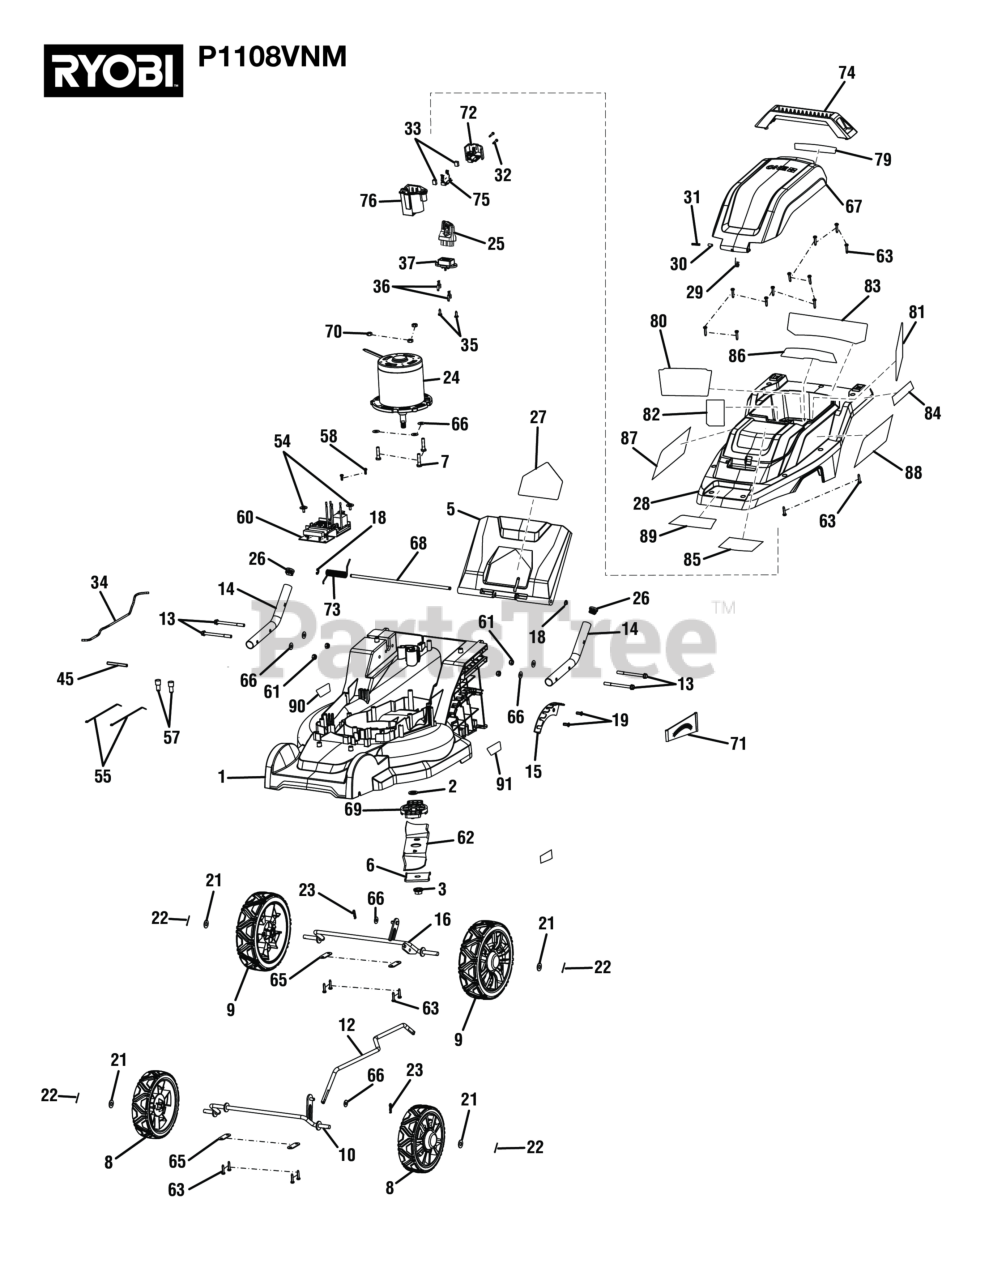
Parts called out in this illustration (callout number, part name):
1	Deck Assembly
2	Flat Washer
3	Blade Nut (M10 x 1.25, Hex Flange Hd.)
5	Rear Door (Inc. Key No. 27)
6	Blade Retainer
7	Bolt (M6 x 26 mm, Hex Hd.)
8	6 in. Wheel Assembly
9	7 in. Wheel Assembly
10	Front Wheel Axle
12	Connector Rod
13	Screw (M6 x 70 mm, Hex Hd.)
14	Tube on Deck
15	Height Adjustment Plate
16	Rear Wheel Axle
18	E-ring (Retaining Ring)
19	Screw (#10-14 x .543 in., T25 Torx Hd.)
21	Washer (ID8.4 x OD18 x 1t)
22	Cotter PinÏ? (2.5)
23	Hitch Pin
25	Start Key
26	Tube Plug
27	Danger Label (No Hands/Feet)
28	Top Cover (Inc. Key Nos. 80-89)
29	Torsion Spring
30	Battery Door Axle
31	Compression Spring
32	Screw (M3 x 16 mm, T10 Torx Hd.)
33	Rubber Cushion
34	Circuit Board to Terminal Wire (Red)
35	Screw (M4.2 x 12 mm, T20 Torx Pan Hd.)
36	Female Terminal
37	Key Holder
45	TUBE, BLK. SHRINKABLE, 5MM
54	Screw w/Washer (M4-18 x 10 mm, T20 Torx Pan Hd.)
55	Cable Tie
57	Wire Connector
58	Screw (M4 x 10 mm, T20 Torx Pan Hd.)
60	Circuit Board
61	Lock Nut (M6 x 6 mm)
62	13 in. Blade
63	Screw (M4 x 18 mm, T20 Torx Pan Hd.)
65	Axle Pressure Plate
66	Washer (ID6.2 x OD15 x 0.08t)
67	Battery Cover (Inc. Key No. 79)
68	Rear Door Shaft
69	Blade Holder
70	Lock Nut (M6)
71	Height Adjustment Plate
72	Press Cover (Battery Connect)
73	Rear Door Torque Spring
75	Plate (Battery Connect)
76	Base (Battery Connect)
79	Icon Label
80	Danger Label (FR)
81	Danger Label (SP)
82	Data Label
83	Danger Label (ENG) w/Warnings
84	Cut Height Label
85	Start Key Warning Label
86	Wet Conditions Label
87	Accent Label (Right)
88	Accent Label (Left)
89	Logo Label
90	13 in. Callout Label (Right)
91	13 in. Callout Label (Left)
